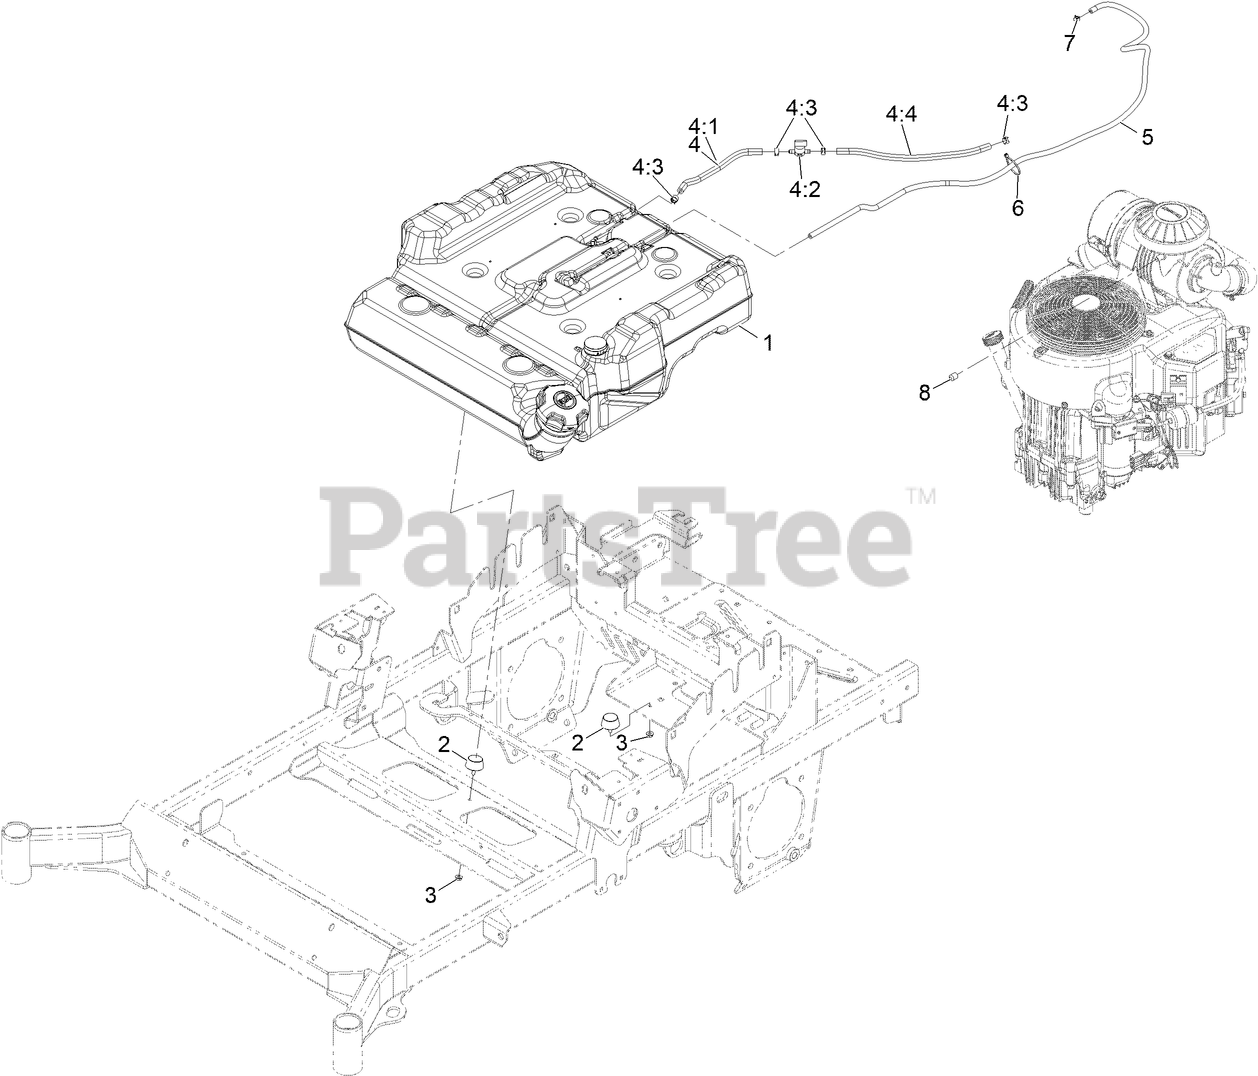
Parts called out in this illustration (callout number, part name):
1	ASM, Fuel Tank
4	ASM, Fuel Line
4:1	Hose-Fuel
4:2	VALVE-FUEL
4:3	CLAMP-HOSE
4:4	HOSE-FUEL
5	Hose-Fuel (.188 X .406 X 40.00)
6	TIE-CABLE
7	CLAMP-HOSE
8	PLUG-PORT
